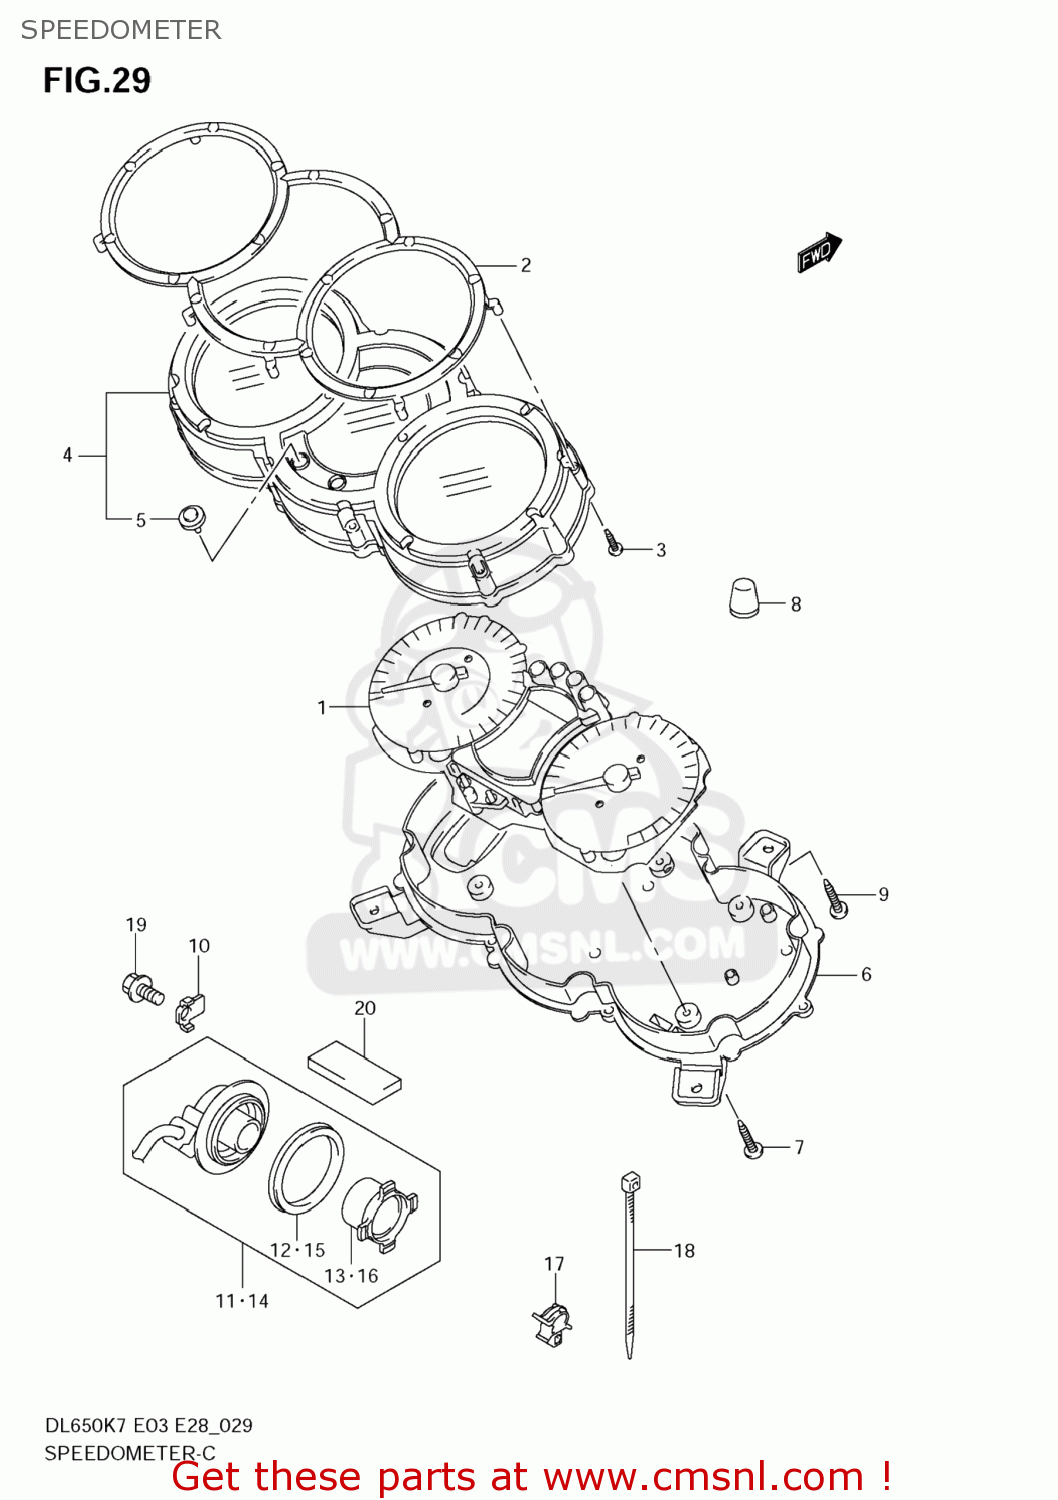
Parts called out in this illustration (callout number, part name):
1	SPEEDOMETER
2	COVER
3	SCREW(2.3X8)
4	CASE,UPR
5	SWITCH,LEVER
6	CASE,LWR
7	SCREW(3X16)
8	CUSHION,SPEEDOMETER
9	SCREW
10	GUIDE,SENSOR LEAD
11	SENSOR,SPEED
12	SEAL,OIL(44X55X6)
13	MAGNETO
14	SENSOR COMP,SPEED
15	SEAL,OIL(44X55X6)
16	MAGNETO
17	CLAMP
18	CLAMP(L:100)
19	BOLT
20	PROTECTOR(18X45X5)
